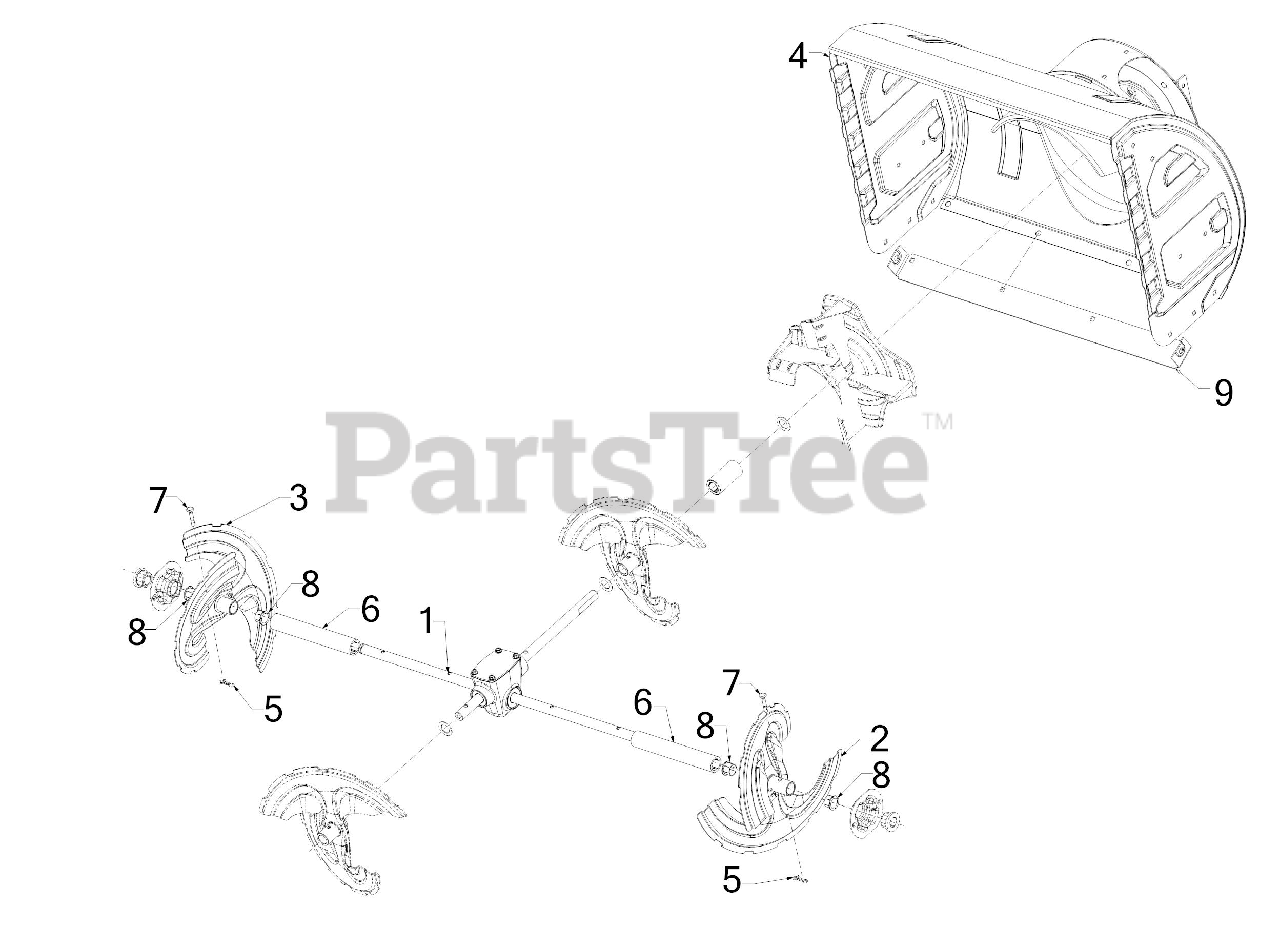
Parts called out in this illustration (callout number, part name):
1	28" AUGER GEARBOX ASSEMBLY
5	BOW TIE COTTER PIN 1/4-5/16
7	SHEAR PIN .25 x 1.50 GR2
8	FLANGE BUSHING
